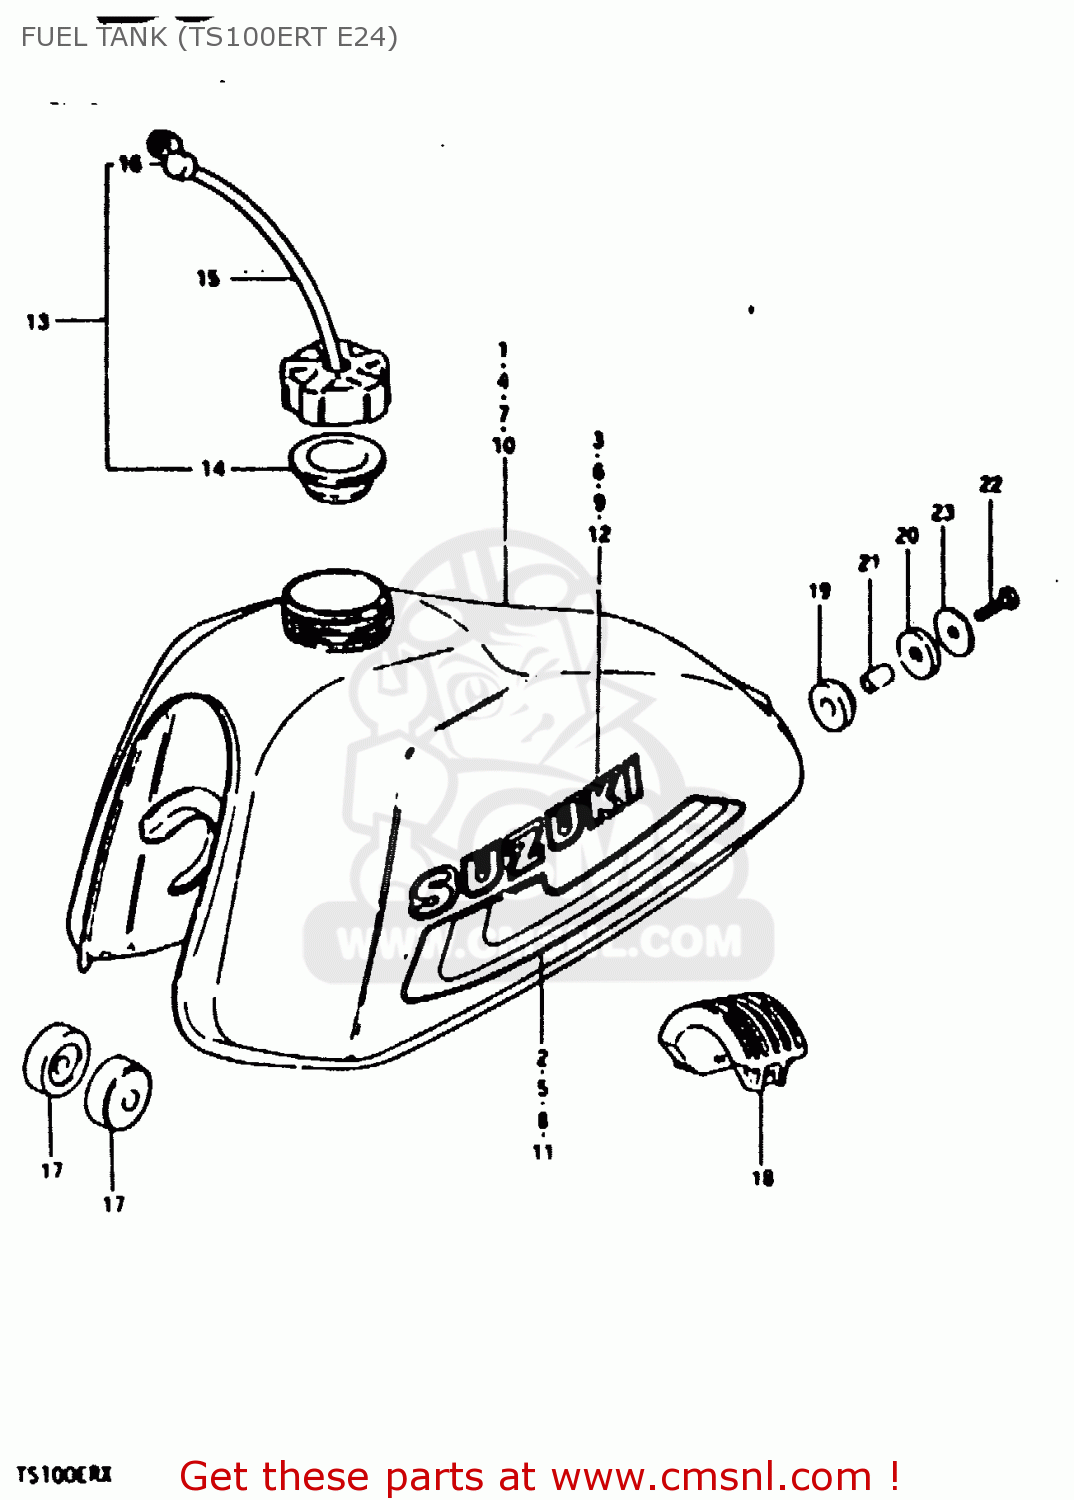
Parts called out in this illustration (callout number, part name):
1	TANK, FUEL (BLUE)
2	EMBLEM,FUEL TANK(WHITE)
3	TAPE SET
4	TANK, FUEL (YELLOW)
5	EMBLEM
6	TAPE SET
7	TANK, FUEL (RED)
8	EMBLEM,FUEL TANK(WHITE)
9	TAPE SET
10	TANK, FUEL (WHITE)
11	EMBLEM
12	TAPE SET
13	CAP SET,FUEL TANK
14	GASKET,FUEL TANK CAP (NAS)
15	HOSE
16	CLAMP,FUEL TANK BREATHER HOSE
17	CUSHION
18	CUSHION,FUEL TANK
19	CUSHION
20	CUSHION
21	SPACER(8.5X12X19)
22	BOLT (8X30)
23	WASHER (8.5X29X1.6)
